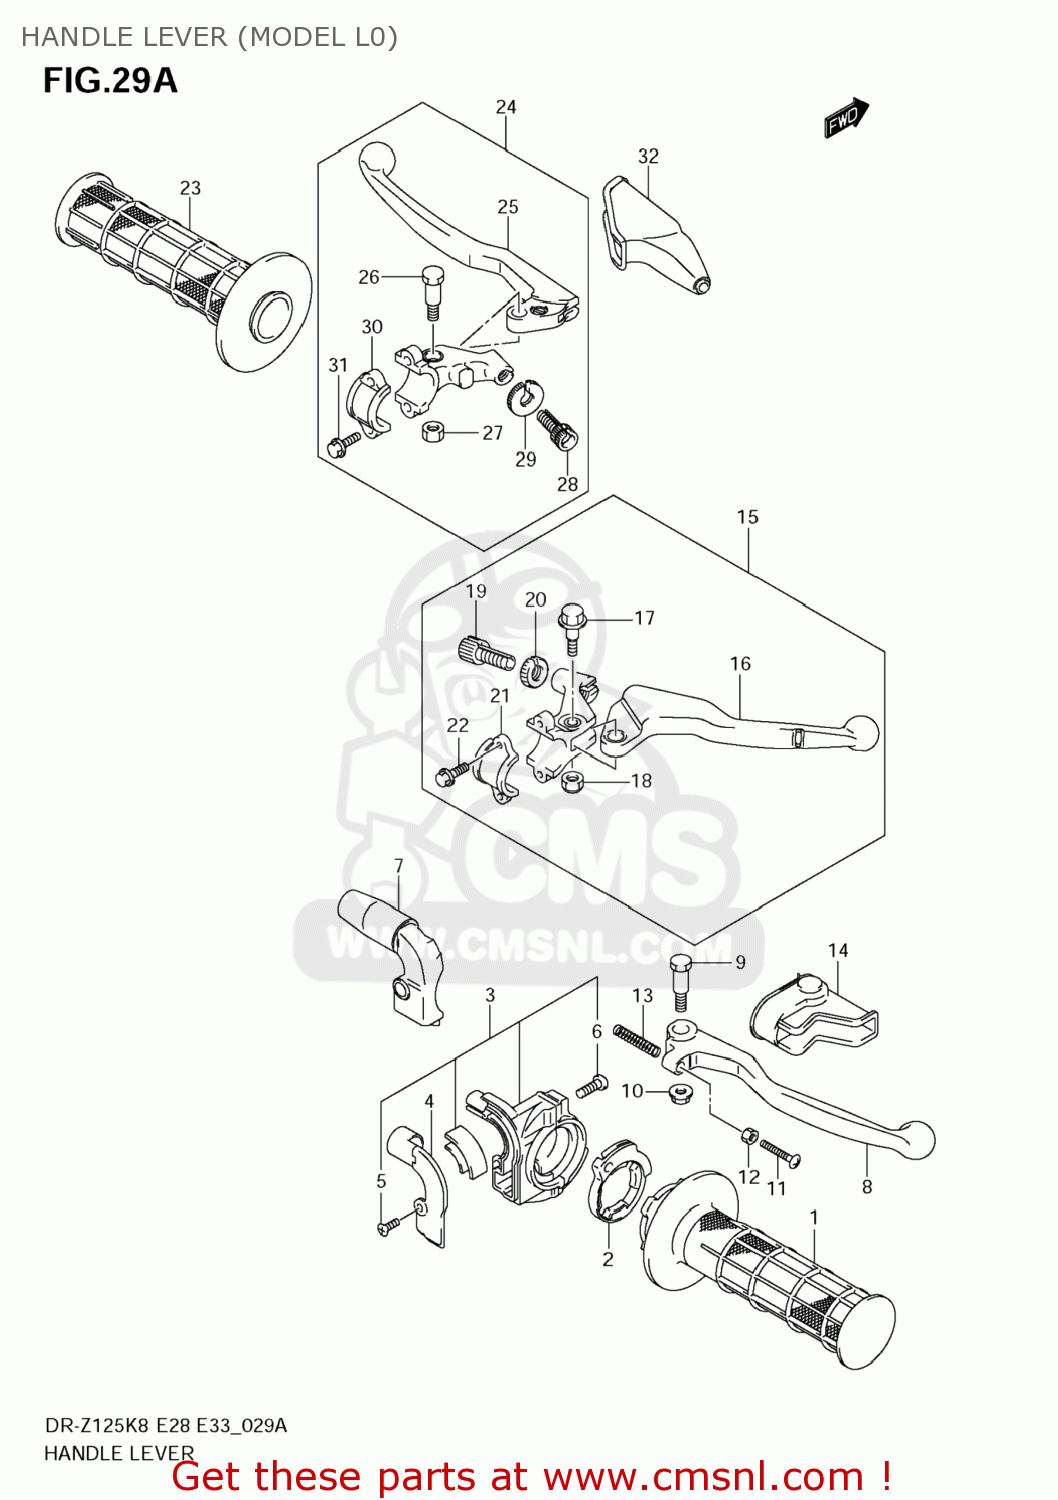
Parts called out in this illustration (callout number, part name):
1	GRIP,THROTTLE
2	ROTER,THROTTLE
3	CASE ASSY,THROTTLE
4	COVER
5	SCREW
6	SCREW
7	COVER,THROTTLE CASE
8	LEVER,BRAKE
9	BOLT,BRAKE LEVER
10	NUT
11	BOLT,ADJUST
12	NUT
13	SPRING,RETURN
14	COVER,BRAKE LEVER
15	LEVER ASSY,BRAKE
16	LEVER,BRAKE
17	BOLT,LEVER PIVOT
18	NUT
19	ADJUSTER,WIRE
20	NUT,LOCK
21	HOLDER
22	BOLT,6X20
23	GRIP,L
24	LEVER ASSY,CLUTCH
25	LEVER,CLUTCH
26	BOLT,LEVER PIVOT
27	NUT
28	ADJUSTER,WIRE
29	NUT,LOCK
30	BRACKET,CLUTCH LEVER HOLDER
31	BOLT,BRACKET
32	COVER,CLUTCH LEVER
